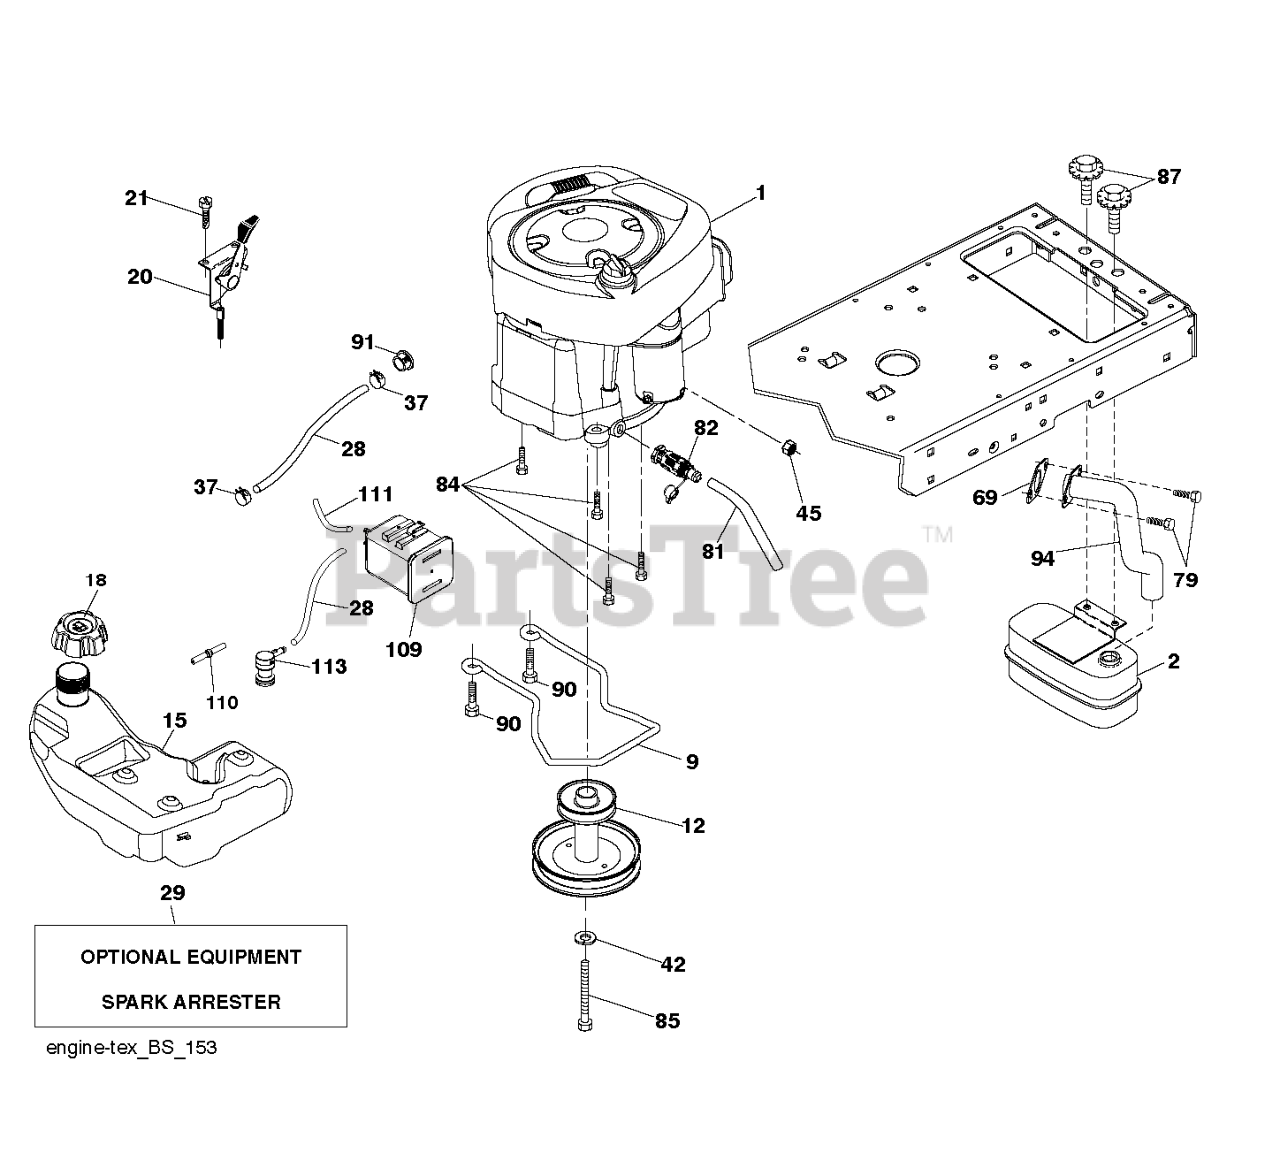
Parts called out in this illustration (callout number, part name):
2	MUFFLER.ASM.SINGLE
9	KEEPER.BELT.ENG.4.25"2.BLT.431
12	ENGINE.PULLEY
15	FUEL TANKS
18	FUEL CAP
18	Fuel Caps
20	CONTROL.TH/CK.C.
28	LINE.FUEL.64"REAR.EMIS
29	KIT.SPARK ARRESTOR 794945 B&S
37	HOSE CLAMP
69	REPL BY 532 27 22-93
81	TUBE, DRAIN OIL ASM.
82	VALUE.OIL.DRAIN
84	SCREW.3/8-16
85	BOLT.HEX.7/16-20X4.GR5.1.5BLUE
87	BOLT.5/16-18UNCX3/4 W/SEMS.BLK
90	SCREW 3/8-16X1
91	BUSHING.1.375OD
94	EXHAUST.TUBE.B&S.28/31
109	CANNISTER, CARBON
110	VALVE.ASM.ANTI-SLOSH
111	TUBE.PURGE.FUEL.1875
113	VALVE.SLANT.CARTRDG.90 DEG.TEX
